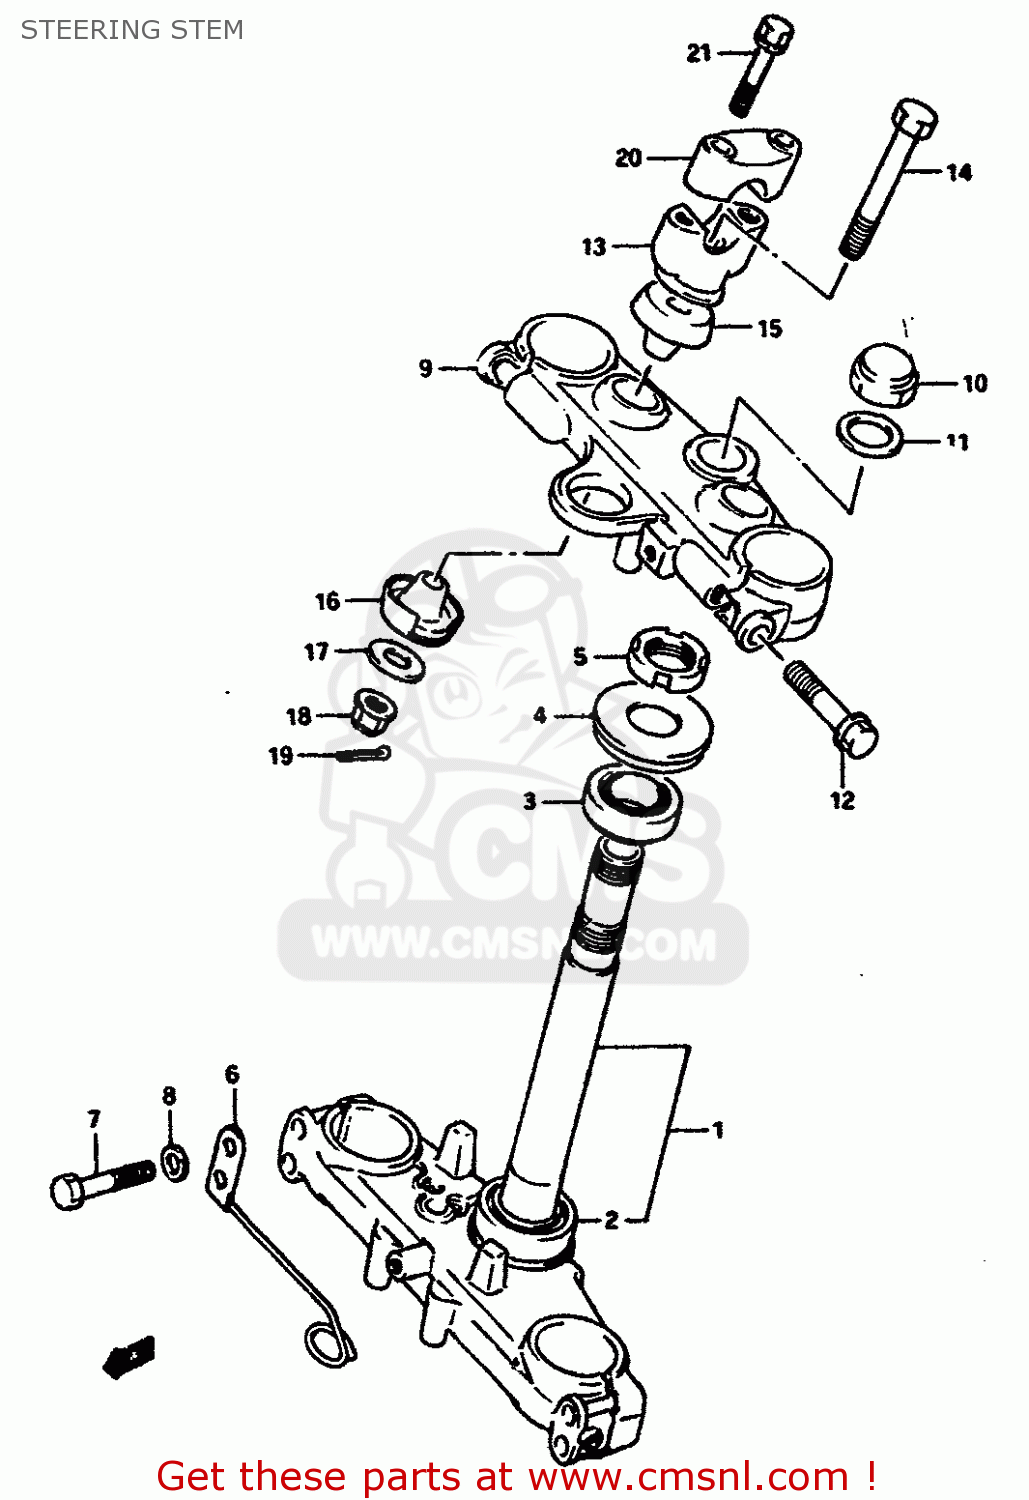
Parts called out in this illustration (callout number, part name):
1	STEM,STEERING
2	BEARING(30X55X17)
3	TAPER,ROLLER BEARING
4	SEAL,STEERING UPR DUST
5	NUT,STEERING STEM
6	GUIDE, SPEEDOMETER CABLE
7	BOLT
8	LOCK WASHER
9	BRACKET,UPPER
10	NUT
11	WASHER,STEERING STEM
12	BOLT
13	HOLDER,HANDLE LWR
14	BOLT,HANDLE HOLDER
15	DAMPER,UPR
16	DAMPER,LWR
17	WASHER,HANDLEBAR HOLDER
18	NUT
19	COTTER PIN
20	HOLDER,HANDLE UPR
21	BOLT
